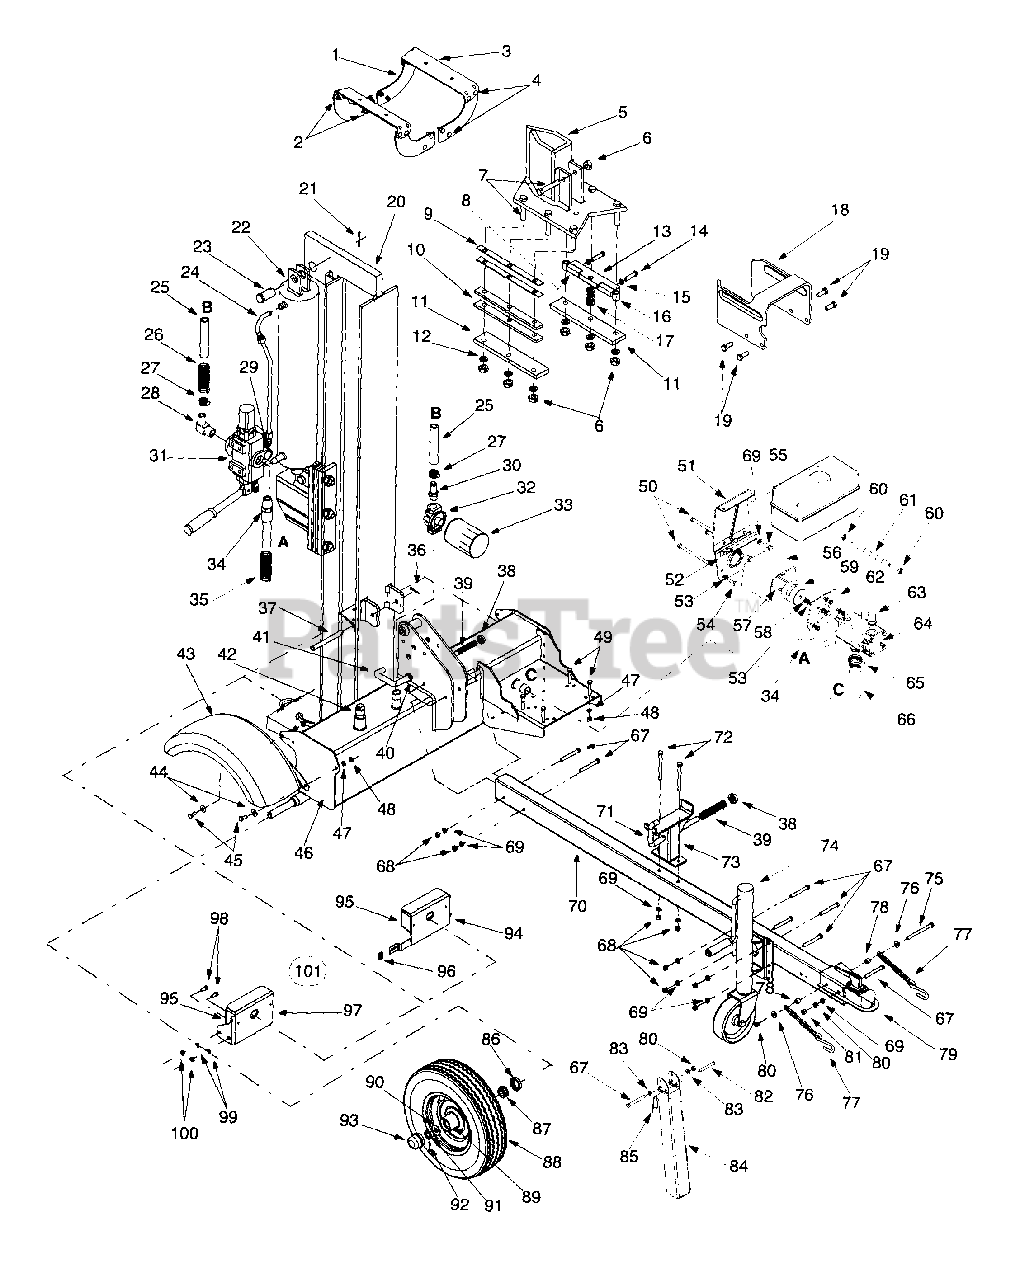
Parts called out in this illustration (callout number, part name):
4	Carriage Bolt 3/8-16 x 1.0
6	Lock Nut 1/2-20
7	Hex Cap Screw 1/2-20 x 2.75
12	Lock Washer 1/2
14	Hex Cap Screw 3/8-24 x 1.5
15	Hex Jam Nut 3/8-24
16	Spacer
17	Flat Washer .531 x .93 x .090
19	Hex Cap Screw 3/8-16 x 1.0
22	Kit Seal 5.0" for Best Metals cylinder 718-0313
22	Hydraulic Cylinder
22	Kit Seal 5.0" for XINGHUI cylinder 718-0313A
22	Kit Seal 5.0" for ENERGY cylinder 718-0313A
23	Clevis Pin
24	Hydraulic Tube
25	Return Hose 3/4" ID x 44" Lg
26	Hose Guard
27	Hose Clamp 5/6"
28	Return Elbow
29	90 Degree Solid Male Adapter
30	3/4" Hose Adapter
32	Filter Housing
33	Oil Filter
34	High Pressure Hydraulic Hose
35	Hose Guard
36	Cotter Pin 1/8" Dia
37	Hinge Pin 1/2 x 4.8" Lg.
38	Push Cap
39	Comp. Spring 4" Lg.
40	Flat Washer .635 ID x .93 OD
41	Locking Rod
42	Pipe Plug
45	Hex Cap Screw 5/16-24 x .75
48	Hex Nut 5/16-24
49	Hex Cap Screw 5/16-24 x 1.
50	Hex Cap Screw 5/16-24 x 5.
51	Fuel Tank Mounting Bracket
52	Fuel Tank Support Bracket
53	Lock Washer 5/16
54	Hex Cap Screw 5/16-24 x 1.0
55	Hex Cap Screw 3/8-16 x 1.0
56	Shoulder Spacer
57	Key
58	Hex Nut 5/16
59	Flex Coupling
60	Hose Clamp
61	Fuel Line Hose
63	Adapter 7/8-14
64	Pump (16 gpm)
65	Hose Clamp
66	Suction Hose
67	Hex Cap Screw 3/8-16 x 3.0
68	Hex Nut 3/8-16
69	Lock Washer 3/8
71	Locking Rod
72	Hex Cap Screw 3/8-16 x 4.0
75	Hex Cap Screw 3/8-16 x 4.25
76	Flat Washer .385 ID x .870 OD
77	Chain
78	Spacer
79	Hitch Coupler
80	Lock Nut 3/8-16
81	Hex Jam Nut 3/8-16
82	Clevis Pin
83	Flat Washer
86	Bearing Seal Only
87	Bearing Cone
88	Wheel Asm Comp - Gray
89	Bearing Cup
90	Flat Washer .76" ID x 1.5" OD
91	Slotted Nut 3/4-16
92	Cotter Pin 5/32" x 1-1/4" Lg.
93	Hub Cap
96	Nut 1/4-20
99	Lock Washer 5/16
100	Hex Nut 5/16-24
101	Taillight Kit
